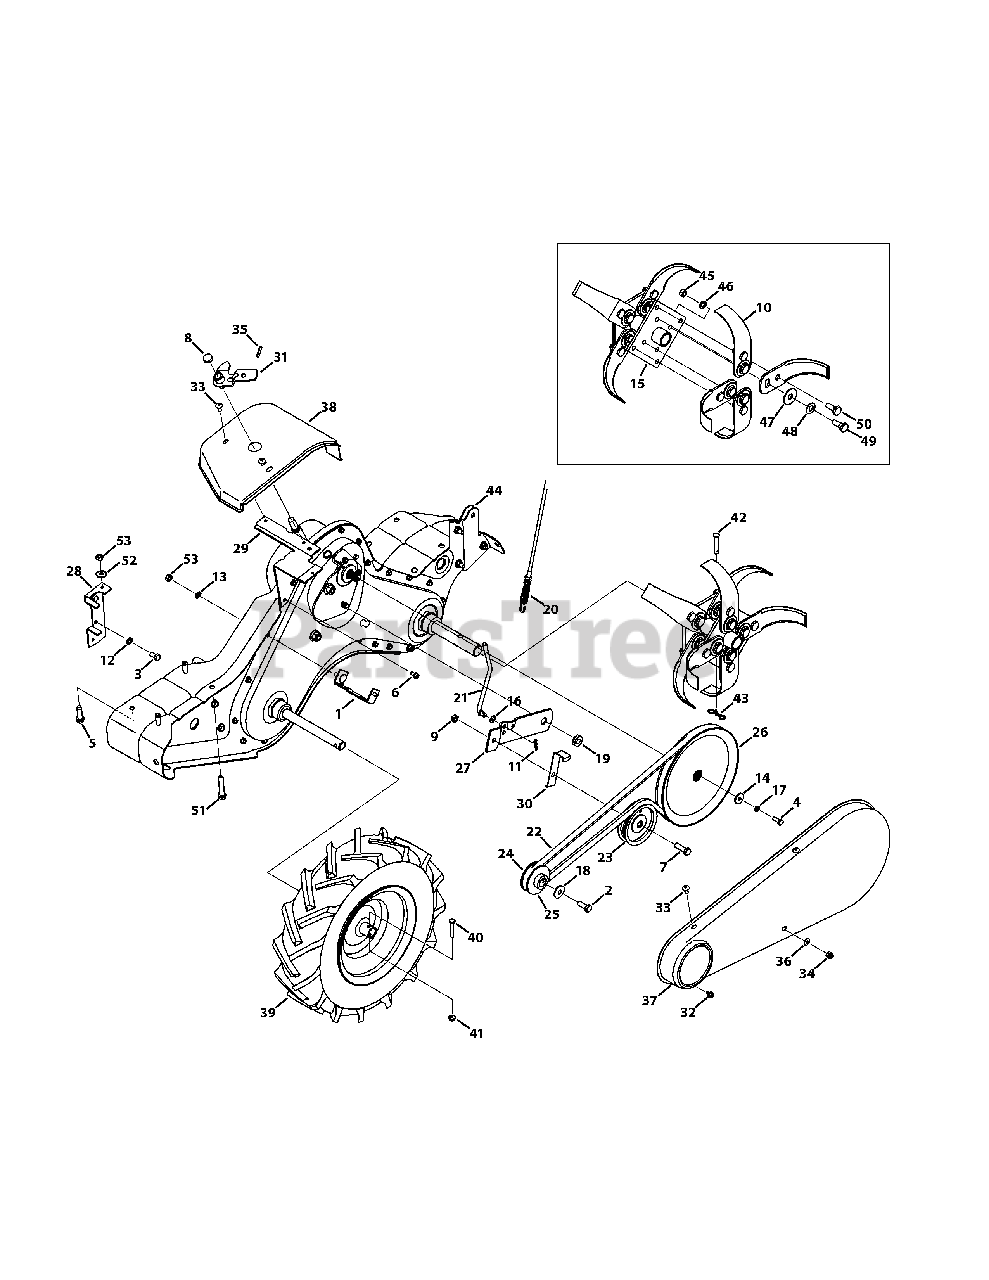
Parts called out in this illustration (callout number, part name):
1	Belt Cover Bracket Assembly
2	Hex Head Screw, 3/8-24 x 1.00
3	Hex Head Screw, 5/16-24 x .625
4	Hex Head Screw, 1/4-28 x .75
5	Screw, 3/8-16 x 1.250
6	Screw, 1/4-20 x 0.500
7	Hex Head Screw, 3/8-16 x 1.25
9	Jam Lock Nut, 3/8-16
10	Articulating Tine
11	Cotter Pin, .072 DIA. x 1.13 LG
12	Washer, Lock, 5/16
13	Washer, Lock, 5/16
14	Washer, Flat, .265 x .938 x .120
15	Tine Adaptor Assembly
15	Tine Assembly
16	Washer, Spring, .317 x .625 x .020
17	Washer, Lock, 1/4
18	Washer, Bell, .396 x 1.140 x .095
19	Shoulder Nut, 7/16-20
20	Clutch Cable
21	Idler Pulley Rod
22	Belt, 4L x 58.16 LG
23	Flat Idler Pulley w/ Flanges, 3.75 O.D.
24	Engine Pulley, Inner Half
25	Engine Pulley, Outer Half
26	Input Pulley, 4L x 8.594
27	Idler Pulley Bracket
28	Belt Keeper Bracket
29	Shift Cover Bracket
30	Idler Belt Keeper
31	Shift Crank Assembly
32	Screw, 1/4-20:0.375
33	Hex Washer Screw, 1/4-14 x .625
34	Lock Nut ,Cap, 1/4-28
35	Spiral Pin, 3/16 x 1.00
36	Washer, Flat, .271 x .630 x .065
37	Belt Cover
38	Shift Cover
39	Wheel, 16 x 4.6 x 8
40	Hex Screw, 1/4-20 x 1.50
41	Flange Lock Nut, 1/4-20
42	Clevis Pin, .375 x 1.75
43	Cotter Pin, Bow Tie
44	Complete Gear Case Assembly
45	Hex Lock Nut, 3/8-24
46	Washer, Lock, 3/8
47	Washer, Flat, .51 x 1.5 x 0.07
48	Washer, Bell, .525 x 1.00 x .050
49	Screw, Shoulder, 3/8-24 x 1/2 x .325
50	Screw, Shoulder, 3/8-24 x 1/2 x .180
51	Hex Head Screw, 5/16-18 x 1.50
52	Washer, Bell, .340 x .872 x .060
53	Hex Nut, 5/16-18
